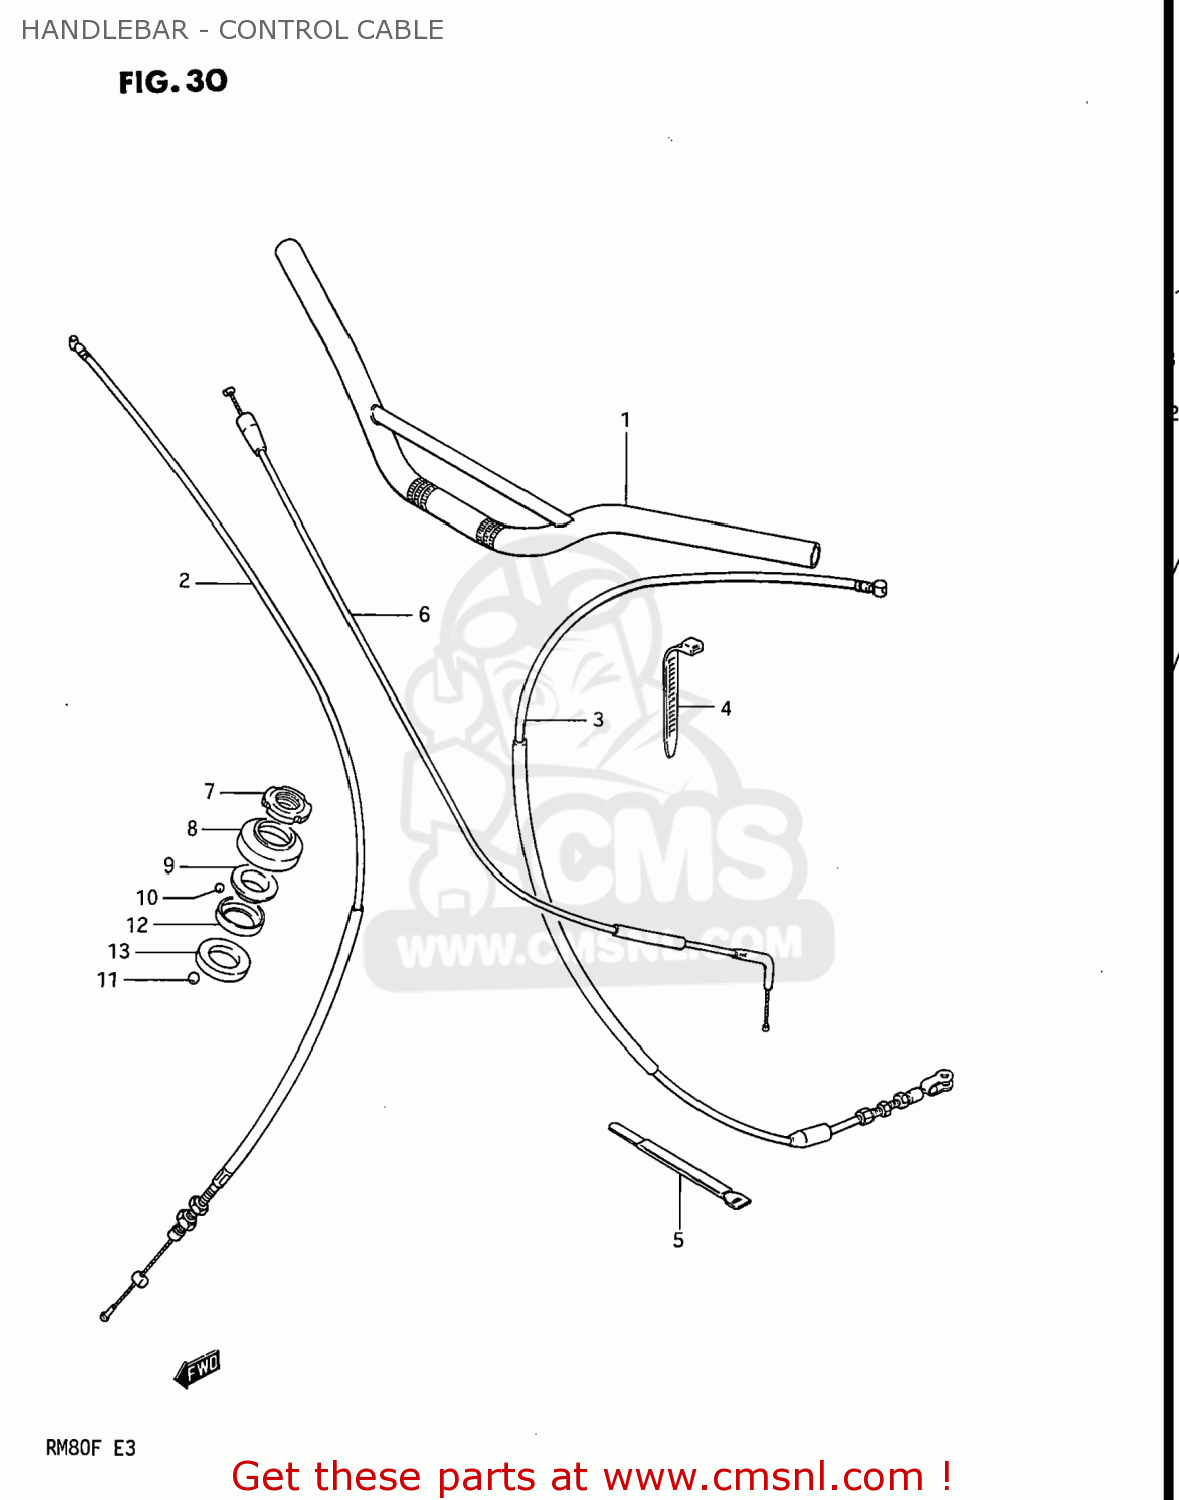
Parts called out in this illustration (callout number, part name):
1	HANDLEBAR
2	CABLE,FR BRAKE
3	CABLE ASSY,CLUTCH
4	CLAMP
5	CLAMP
6	CABLE ASSEMBLY,THROTTLE
7	NUT,STEERING STEM(25X44X10)
8	DUST SEAL,STEERING UPR
9	RACE,STEERING OUTER UPR
10	BALL
11	BALL
12	RACE,STEERING INNER UPR
13	LACE,STEERING INNER LWR
